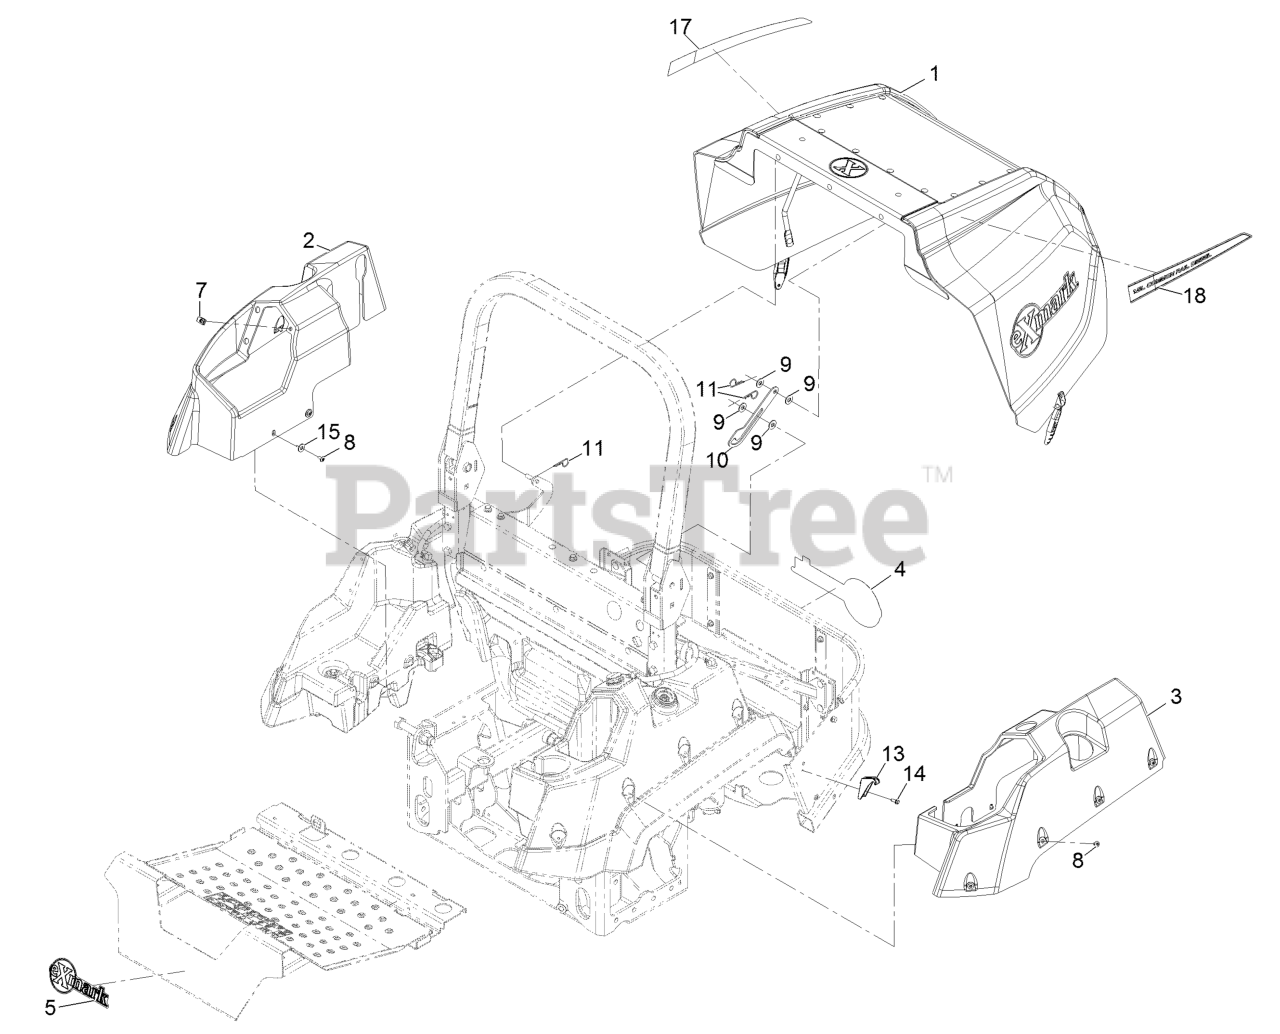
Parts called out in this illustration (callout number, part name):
1	Hood ASM
2	Cover-Tank, RH
3	Cover-Tank, LH
4	Decal-Exmark
5	Decal-Exmark
7	Nut-Retainer-Panel 1/4-20
8	Screw-Torx
9	Washer-3/8 Std
10	Prop-Hood
11	Pin-Cotter, Hair
13	Latch-Catch
14	Screw-HWH 1/4-20 X .62
17	Decal-Common Rail Diesel-RH
18	Decal-Common Rail Diesel-LH
